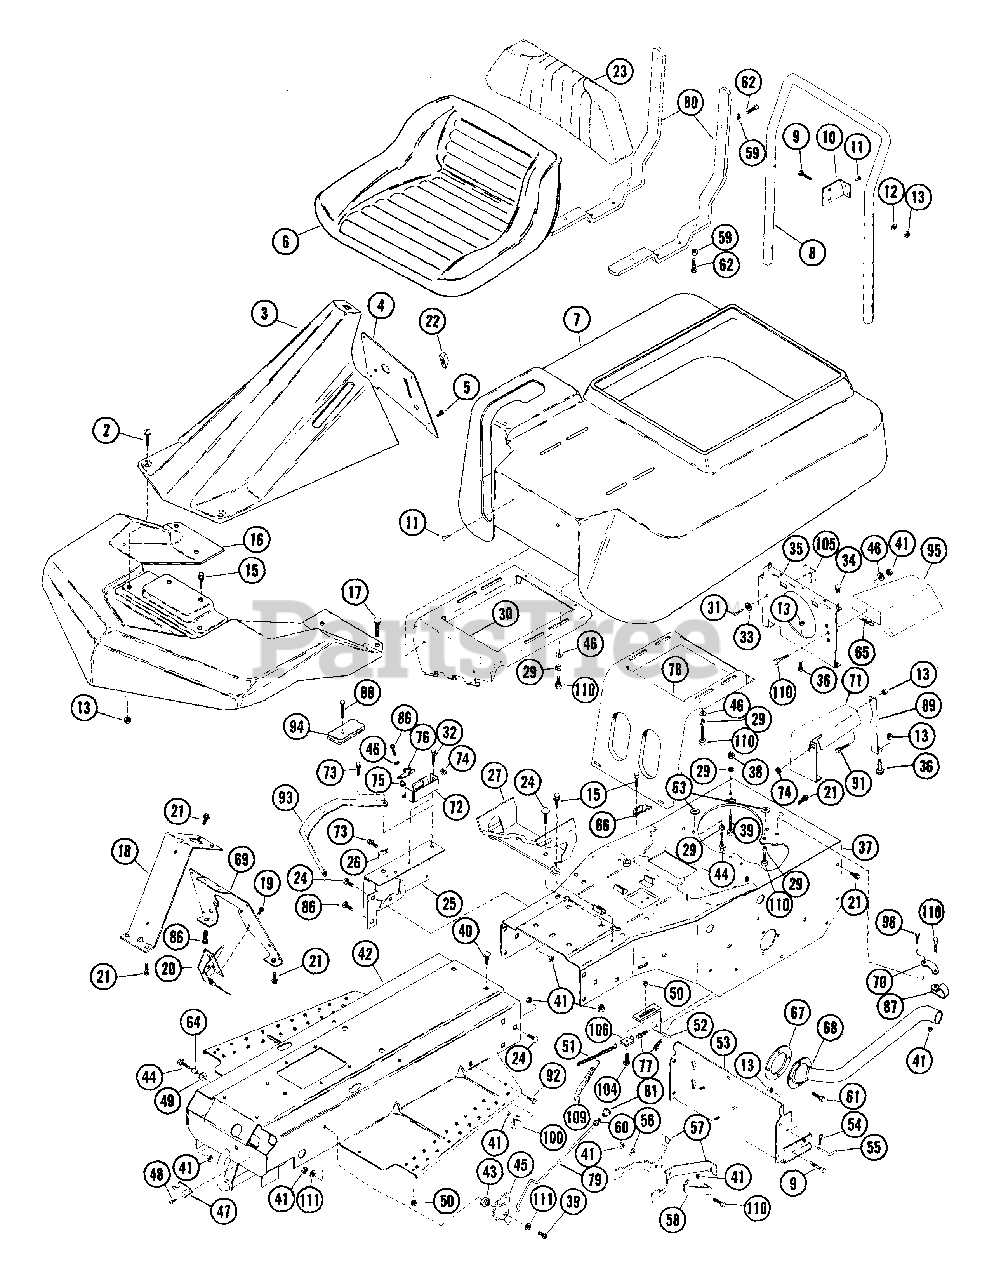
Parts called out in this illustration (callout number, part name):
2	SCR-MCH .25-20X.63 CRPH PL
4	CONTROL PANEL ASSEMBLY
5	SCR-TAP 10-12X.50 CRPH PL A
6	SEAT
7	ENGINE COVER ASSEMBLY
8	SERVICE BAR
9	BLT-HEX .25-20X1.50 PL GR5
10	BRACKET
11	RVT-POP .187X.402 DOME ST
12	WSHR-FL-STL.312X.734X.065PL
13	NUT-LK-CTR .250-20 PL
15	BLT-SERHFWH .25-20X.50 PL
16	FRONT WHEEL COVERS
17	SCR-SLTR-SERNK .25-20X.62 PL
19	SCR-TAP 10-24X.375 CRPH 1A
20	THROTTLE CONTROL
21	BLT-SERHFWH .31-18X.50 PL
23	SEAT BACK
24	BLT-RDHDSQSHNK .31-18X.50 YZ
25	SHIFT QUADRANT
26	CLIP
27	SEAT HINGE
28	BLT-HEX .31-18X1.50 PL GR2
29	WSHR-LK .312X.097 PL HVY
30	BRACKET
31	SCR-TAP 10-16X1.0 SLHP PL AB
32	SCR-TAP 10-24X.375 CRPH 1A
33	WSHR-FL-STL .250X.562X.049 PL
34	BUMPER GROMMET
35	SEAT LEG
36	BLT-HEX .25-20X.50 PL GR2
37	FRAME
38	NUT-HEX .312-18
39	BLT-HEX .31-18X1.25 PL GR2
40	BLT-RDHDSQNK .312-18X.62 PL
41	NUT-LK .312-18 GR A PL
42	FRONT FRAME ASSY.
43	SPACER -SHLD .344X.500X.469
44	BLT-HEX .31-18X1.00 PL GR 2
45	BRAKE LATCH
46	WSHR-FL-STL.312X.734X.065PL
47	LOCK SPRING
48	SCR-TAP 10-12X.50 CRPH PL A
49	WSHR-FL-STL .323X.625X.062 PL
50	NUT-LK-FLG .250-20 PL
51	BRAKE CHAIN
52	BRACKET
54	PIN-HAIR INT .09X.188 PL
55	PIN
56	WSHR-FL-STL .323X.625X.062 PL
57	BELT FINGER
58	BELT FINGER BRACE
59	WSHR-LK .250X.077 HVY PL
60	NUT-LK TOP 10-24 PL
61	SCR-TAP 8-32X.38 SL HWH PL 23
62	BLT-HEX .25-20X1.00 GR2
63	WSHR-FL-STL .328X.875X.062 PL
64	SPACER .344X1.000X.375
65	PIN-HAIR INT .08X.18X1.18
66	CLAMP
67	GASKET
68	EXHAUST PIPE
69	SUPPORT
71	SHIELD
72	SWITCH HOUSING
73	BLT-SCRHFWH .25-20X.62 PL
74	GROMMET, .31 ID
75	BSHG, FLG .325X.499X.26X.88
76	CAM NO SCRAP
77	BLT-SERHFWH .25-20X.50 PL
78	SEAT BRACKET
79	PARKING BRAKE ROD
80	SEAT BRACE
86	BLT-SERHFWH .31-18X.75 PL
88	SCR-TAP 12-14X1.25 CROVH PL 1A
89	SWITCH HOUSING
91	BLT-HEX .25-20X.38 PL GR2
92	BLT-HEX .31-18X.50 PL GR2
93	SHIFT PANEL
95	BAFFLE
96	BLT-SCRHFWH .38-16X.75 PL
104	BLT-RDHDSQNK .25-20X.62 PL
105	CLAMP
106	BRACKET
109	SG-TENS .041X.35X2.11 WLD 8
110	BLT-HEX .31-18X.75 PL GR2
111	WSHR-FL-STL .38X.875X.083 PL
